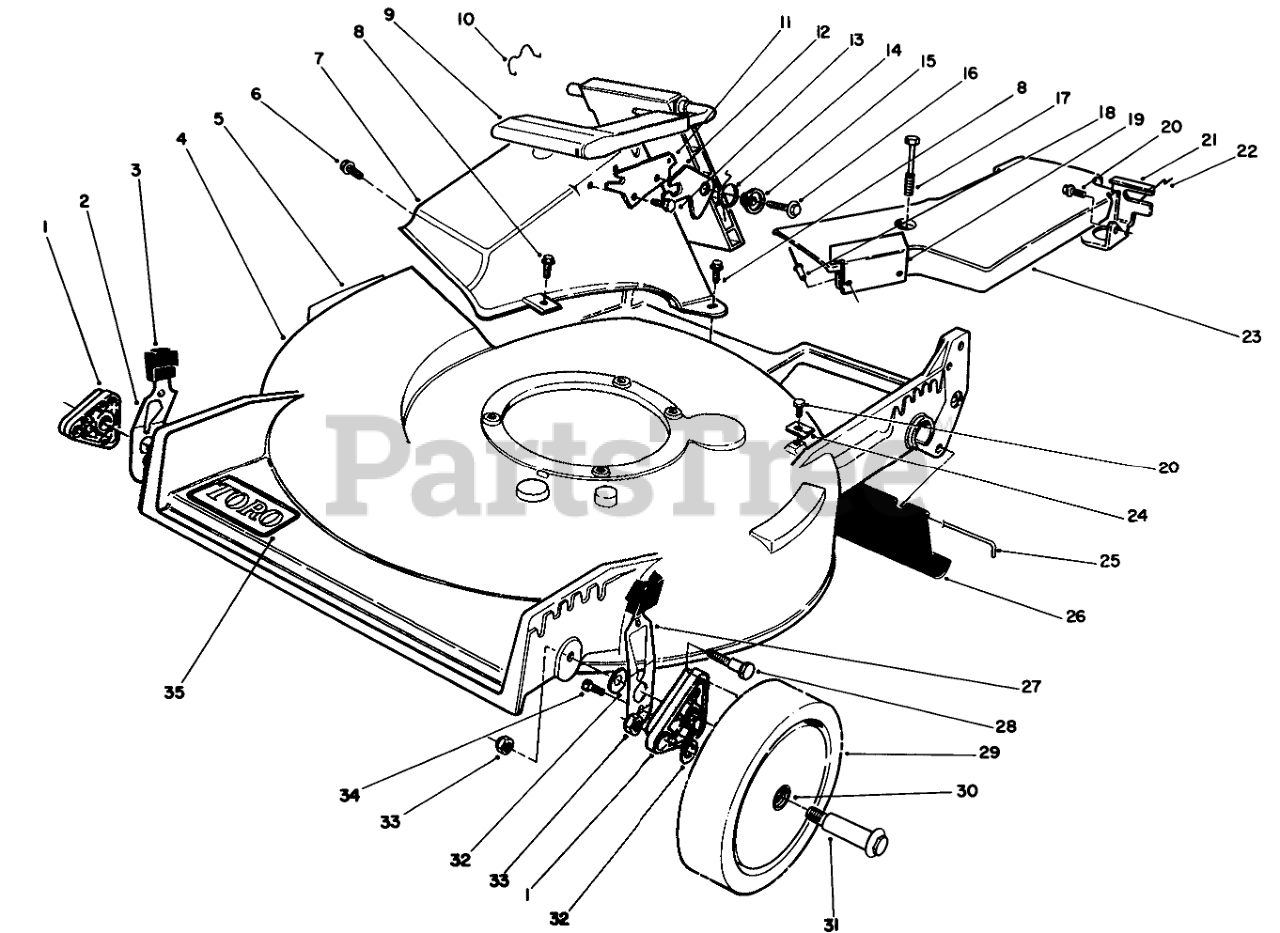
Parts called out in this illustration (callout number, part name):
1	ARM-PIVOT, FRONT
2	RH SPRING ARM ASSEMBLY
3	KNOB-ARM
4	Housing (Incl. Ref. #1 & 35)
5	DECAL-DANGER
6	SCREW AND WASHER ASM
7	Tunnel Discharge
8	SCREW-HWH
9	Discharge Door Assembly
10	DOOR RET SPRING
11	DOOR LATCH PLATE
12	SAFETY LATCH
13	SCREW-PLASTITE
14	TORSION SPRING
15	DOOR SPACER
16	SCREW-HWH
17	SCREW-HHFTF
18	RIVET-HEAD, FLAT
19	HEAT SHIELD
20	SCREW-HWHTF
21	Bracket-Traction Adj.
22	RETAINER-CABLE
23	Belt Cover Assembly (Incl. Ref. #18 & 19)
24	CLAMP-CABLE
25	Rod Shield
26	SHIELD-TRAILING
27	LH SPRING ARM ASSEMBLY
28	BOLT-SHOULDER
29	Wheel & Tire Assembly (Incl. Ref. #30)
30	BUSHING
31	WHEEL BOLT
32	WASHER
33	Nut
34	SCREW-HWH
35	DECAL
